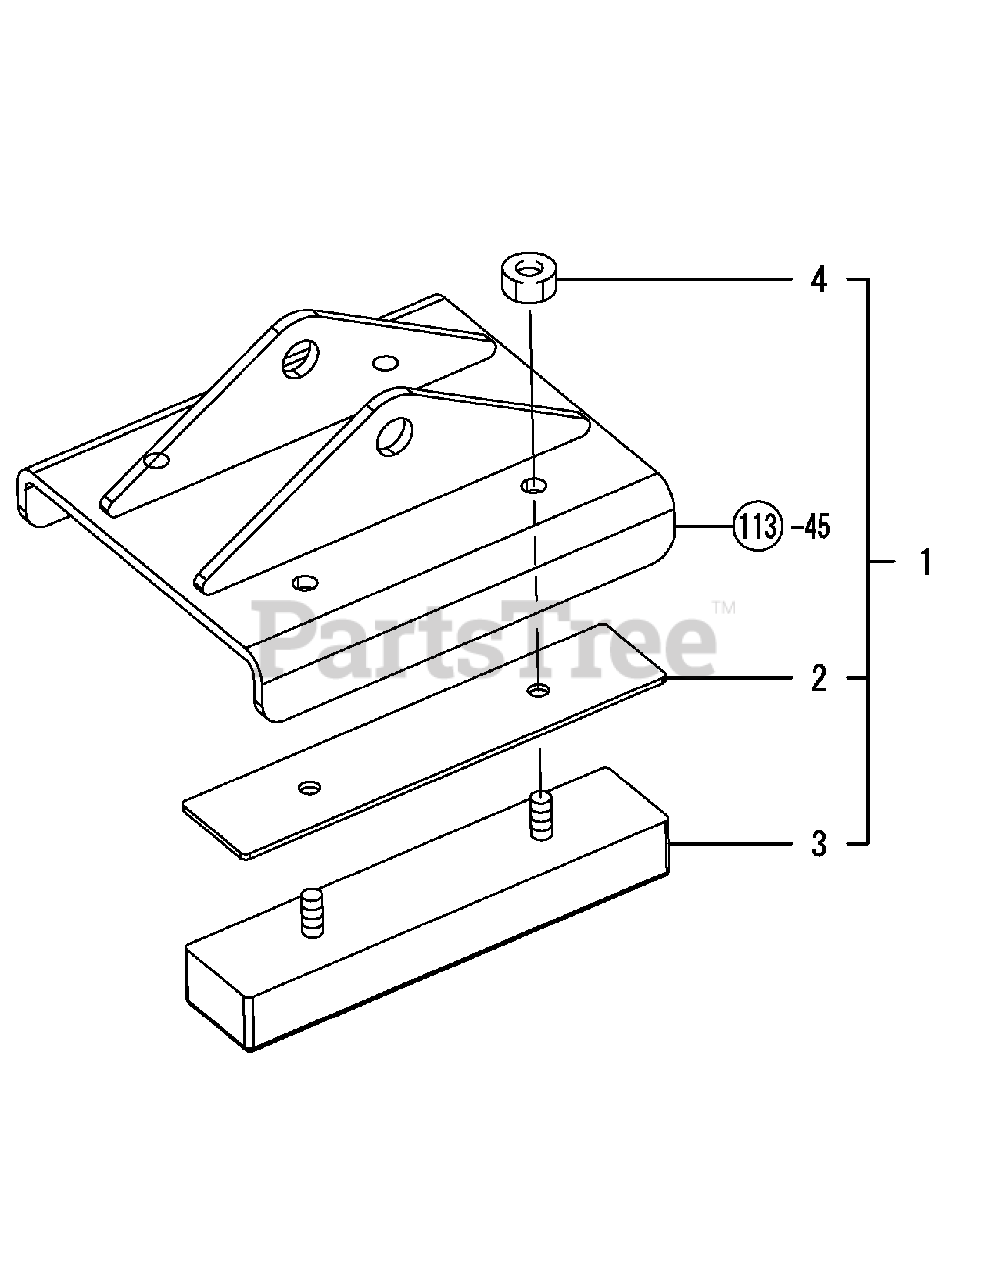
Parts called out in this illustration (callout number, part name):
1	STREET PAD KIT
2	STREET PAD SPACER
3	STREET PAD RUBBER
4	NUT, LOCK NF 38
